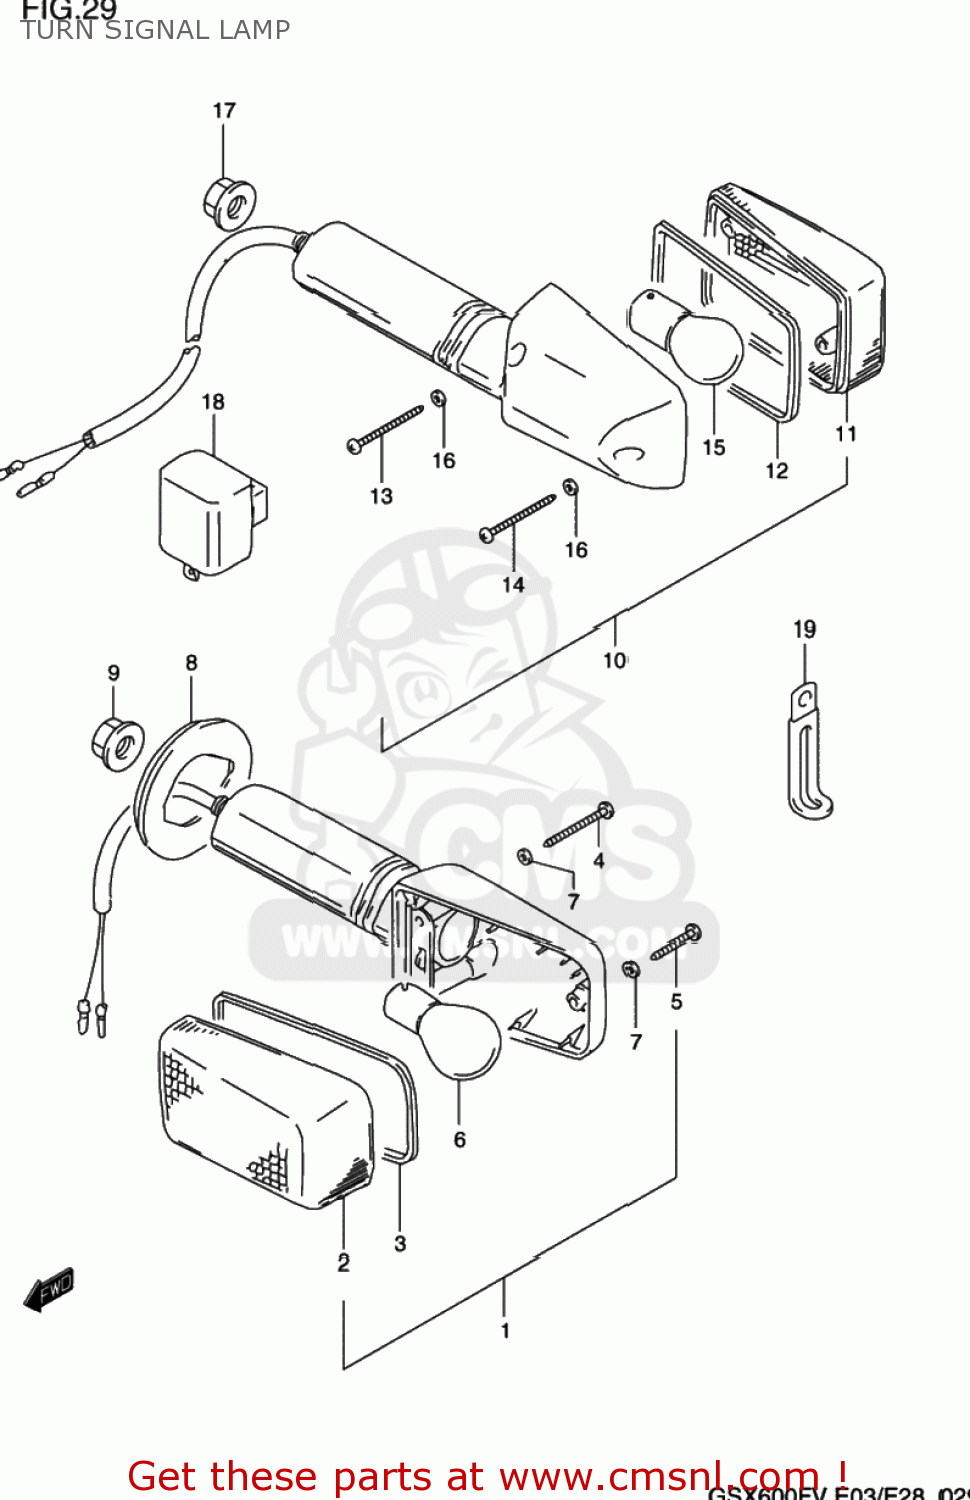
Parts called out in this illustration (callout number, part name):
1	LAMP ASSY,FR TURN SIGNAL
2	LENS
3	GASKET (NAS)
4	SCREW(3X30)
5	SCREW
6	BULB(12V21W)
7	GASKET (NAS)
8	GROMMET
9	NUT
10	LAMP ASSY,RR TURNSIGNAL
11	LENS
12	GASKET (NAS)
13	SCREW(3X30)
14	SCREW
15	BULB(12V21W)
16	GASKET (NAS)
17	NUT
18	RELAY ASSY,TURNSIGNAL LAMP
19	CLAMP(L:45)
